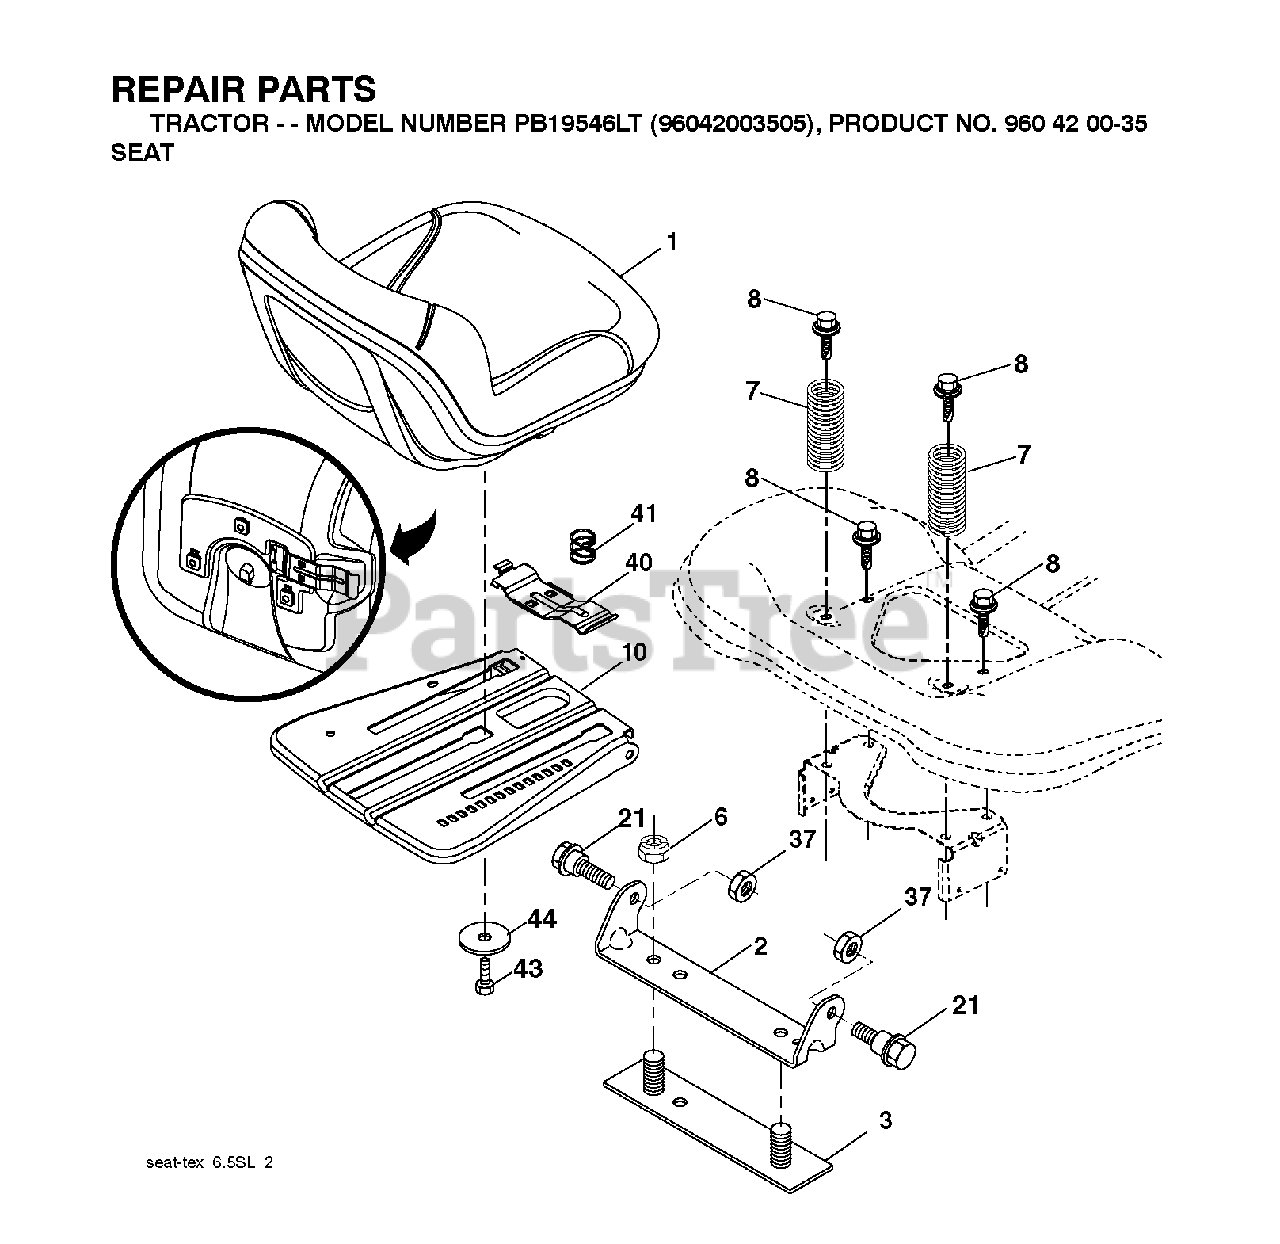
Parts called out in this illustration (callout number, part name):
2	BRKT.PIVOT.FENDER
6	NUT
7	SPRING COMPRESSION
8	BOLT, 5/16-18 X 1 3/4
10	PAN.ASM.SEAT.3PT
21	BOLT.SHOULDER.5/16-18
37	NUT.71038.31-18.HEX.NYLOCK
40	HANDLE.SLIDE.SEAT.TEX.BLACK
41	SPRING.LATCH.SEAT.TEX
44	WASHER 13/32 X 2-3/8 X 12GA
